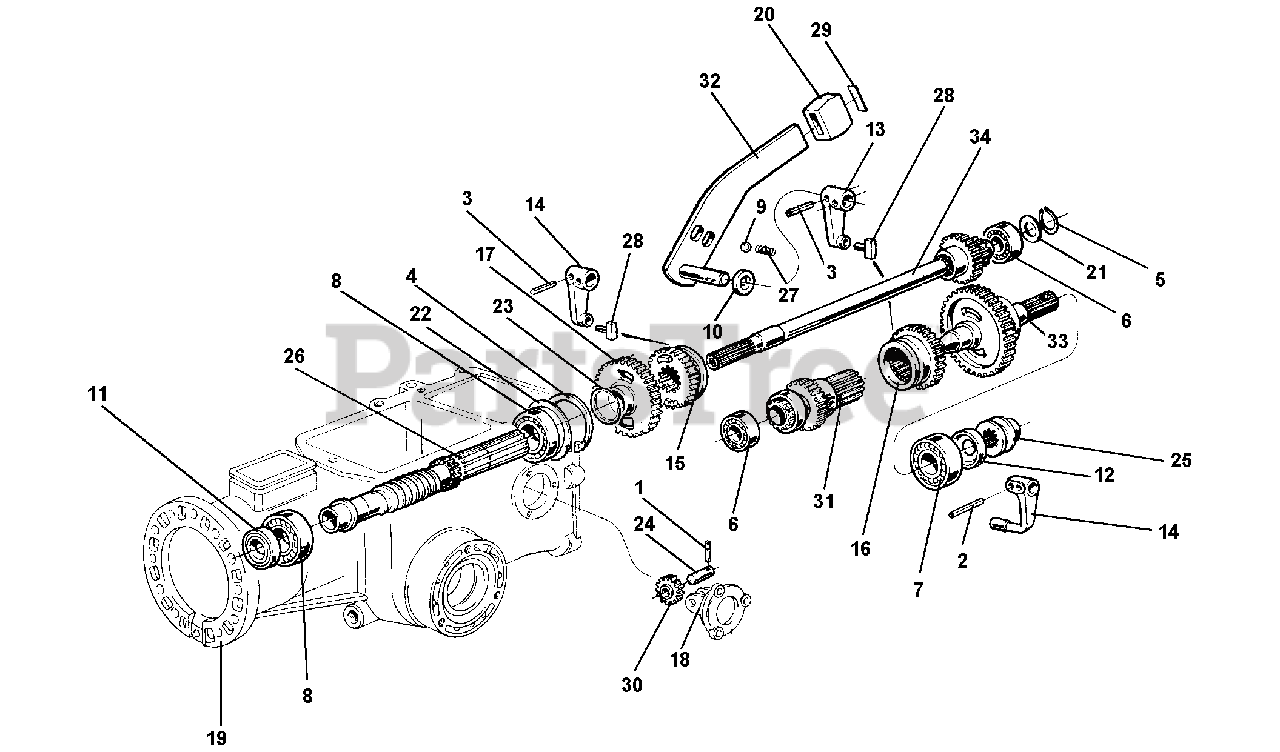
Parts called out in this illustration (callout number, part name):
1	PIN, LOCKING 2.5 X 22 DIN 1481
2	LOCKING PIN 4 X 20 SPIRAL
3	LOCKING PIN 4 X 24 SPIRAL
4	CIRCLIP, INTERN D 52
6	BEARING 15 X 35 X 11 6202
7	BEARING 20 X 47 X 14 6204
8	BEARING SKF 25 X 52 X 15 6205
9	BALL 15/32 RIV RB-11.906
10	SEAL, OIL 12 X 19 X 5 STANDARD
11	SEAL, OIL 15 X 40 X 10 STANDARD
12	SEAL, OIL 20 X 35 X 7 STANDARD
13	LEVER, SPEED CHG SLDG GR
14	SLIDE LEVER
15	SLIDER SPEEDS
16	SLIDER REDUCTION UNIT
17	WHEELS FIRST SPEED
18	FLANGE, REVERSE SPEED
19	CASING 5 SPEEDS GEARBOX
20	KNOB REDUCTION UNIT LEVER
21	WASHER 15.1 X 25 X 2
22	RING C - 72
23	WASHER 25 X 32 X 2 C - 72
29	PLATE SLOW/FAST SPEEDS
30	REVERSE SPEED GEAR
31	GEAR TRIPLE
32	LEVER REDUCTION UNIT
33	P.T.O. SHAFT
34	CLUTCH SHAFT
